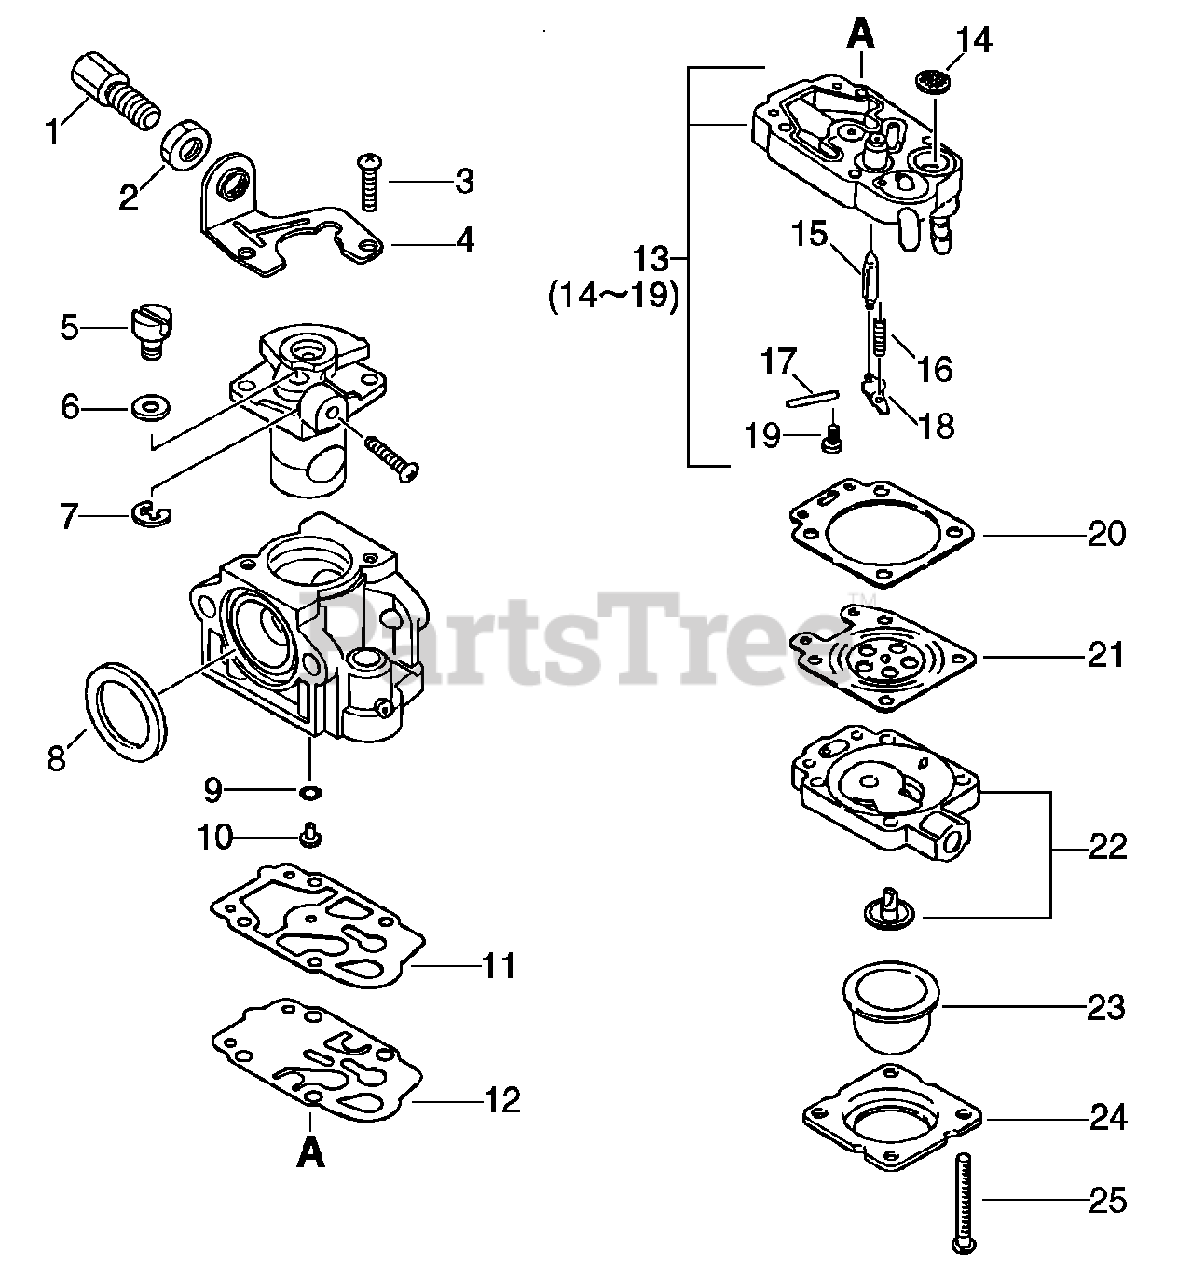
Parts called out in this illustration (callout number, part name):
1	NUT, CABLE ADJUST
4	BRACKET, THROTTLE CABLE
7	RING, RETAINING
10	JET, MAIN
11	GASKET, PUMP
12	DIAPHRAGM, PUMP
13	BASE, PURGE
14	STRAINER
15	VALVE, INLET NEEDLE
16	SPRING, METERING LEVER
17	PIN, METERING LEVER
18	LEVER, METERING
19	SCREW, METERING LEVER PIN
20	GASKET, METERING
21	DIAPHRAGM, METERING
22	PURGE BASE ASSY
23	BULB, PURGE
24	RETAINER, PURGE BULB
25	SCREW, PUMP COVER
